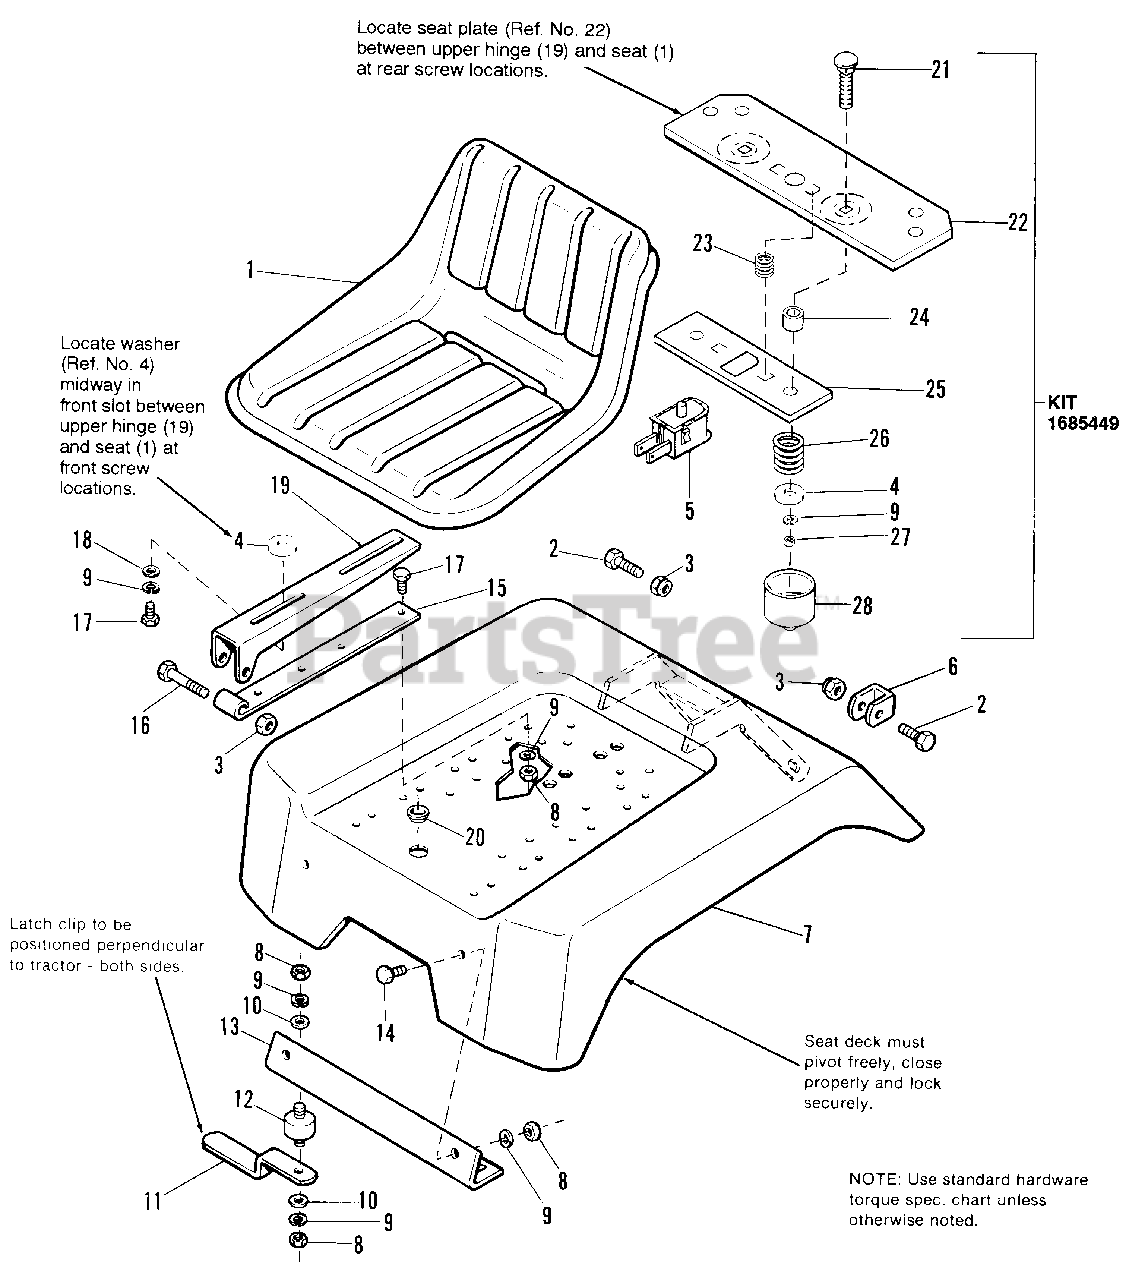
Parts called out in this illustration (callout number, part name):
2	CAPSCREW, Hex Hd., 3/8-16 x 1-1/4
3	LOCKNUT, Hex, 3/8-16
5	SWITCH, Seat
6	STOP, Seat Deck
7	DECK ASSY., Seat
8	NUT, Hex, Full, 5/16-18
9	LOCKWASHER, 5/16
10	WASHER, Plain, 1/4
12	CONNECTOR, Cushion
13	BRACKET, Seat Deck, Front
14	CAPSCREW, Hex Hd., 5/16-18 x 5/8
15	HINGE, Lower
16	CAPSCREW, Hex Hd., 3/8-16 x 2
17	CAPSCREW, Hex Hd., 5/16-18 x 3/4
18	WASHER, Plain, 5/16
19	HINGE, Upper
20	BUSHING, Snap
21	CARRIAGE BOLT, 5/16-18 x 1-1/4
22	PLATE, Seat
25	PLATE, Switch
27	NUT, Lock, 5/16-18
28	COVER, Spring
